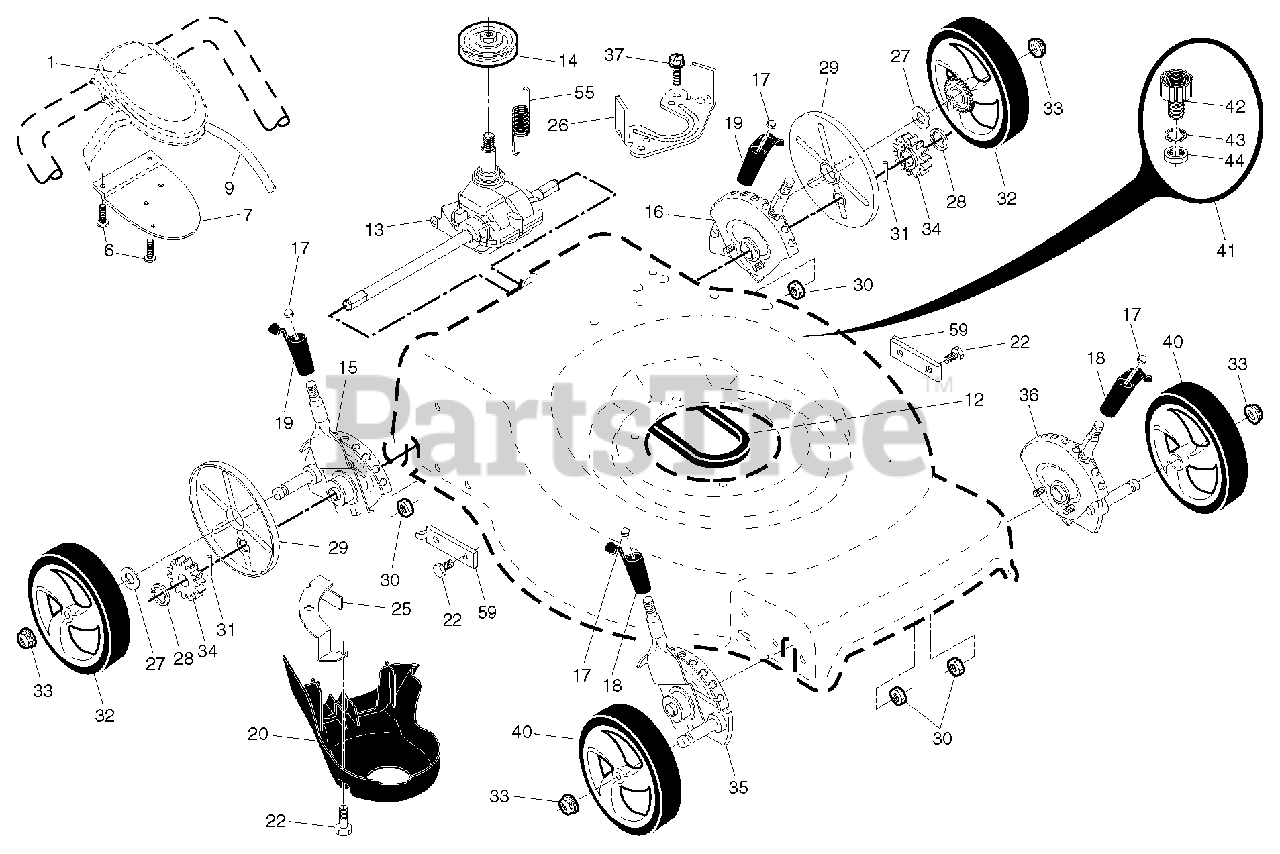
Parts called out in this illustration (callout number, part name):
6	SCREW, PHILLIPS HEAD 10 X 5/8
7	BRACKET.DRIVE.CONTROL.MOUNT
12	BELT.DRIVE.RGD.PLUS
13	TRANSMISSION.22+.RGD.AW2/EZ2
20	COVER.BELT.22.RGD
22	BOLT.5/16HEX.WHS.HD
25	BRACKET.DRIVE.COVER.RGD.BZP
26	BRACKET.TRANS.BELT.KEEPER.BZP
27	WASHER FLUT
28	E-RING 7/16 RE
29	COVER.DUST.WHEEL
30	NUT.HEX.FLANGE.1/4
31	PAWL, DRIVE
33	NUT.HEX.FLANGE.3/8-16.LOCKNUT
34	PINIION.14.TOOTH.RGD
40	WHEEL.8X1.75.MAG.CLOSE.BLACK
41	KIT.WASH-OUT.PORT
42	FITTING, HOSE, WATER WASHOUT
43	WASHER.LOCK.INTERNAL.TOOTH
44	LOCKNUT.HEX.WITH.O-RING
59	BRACKET.SUPPORT.22+RWGD.BZP
